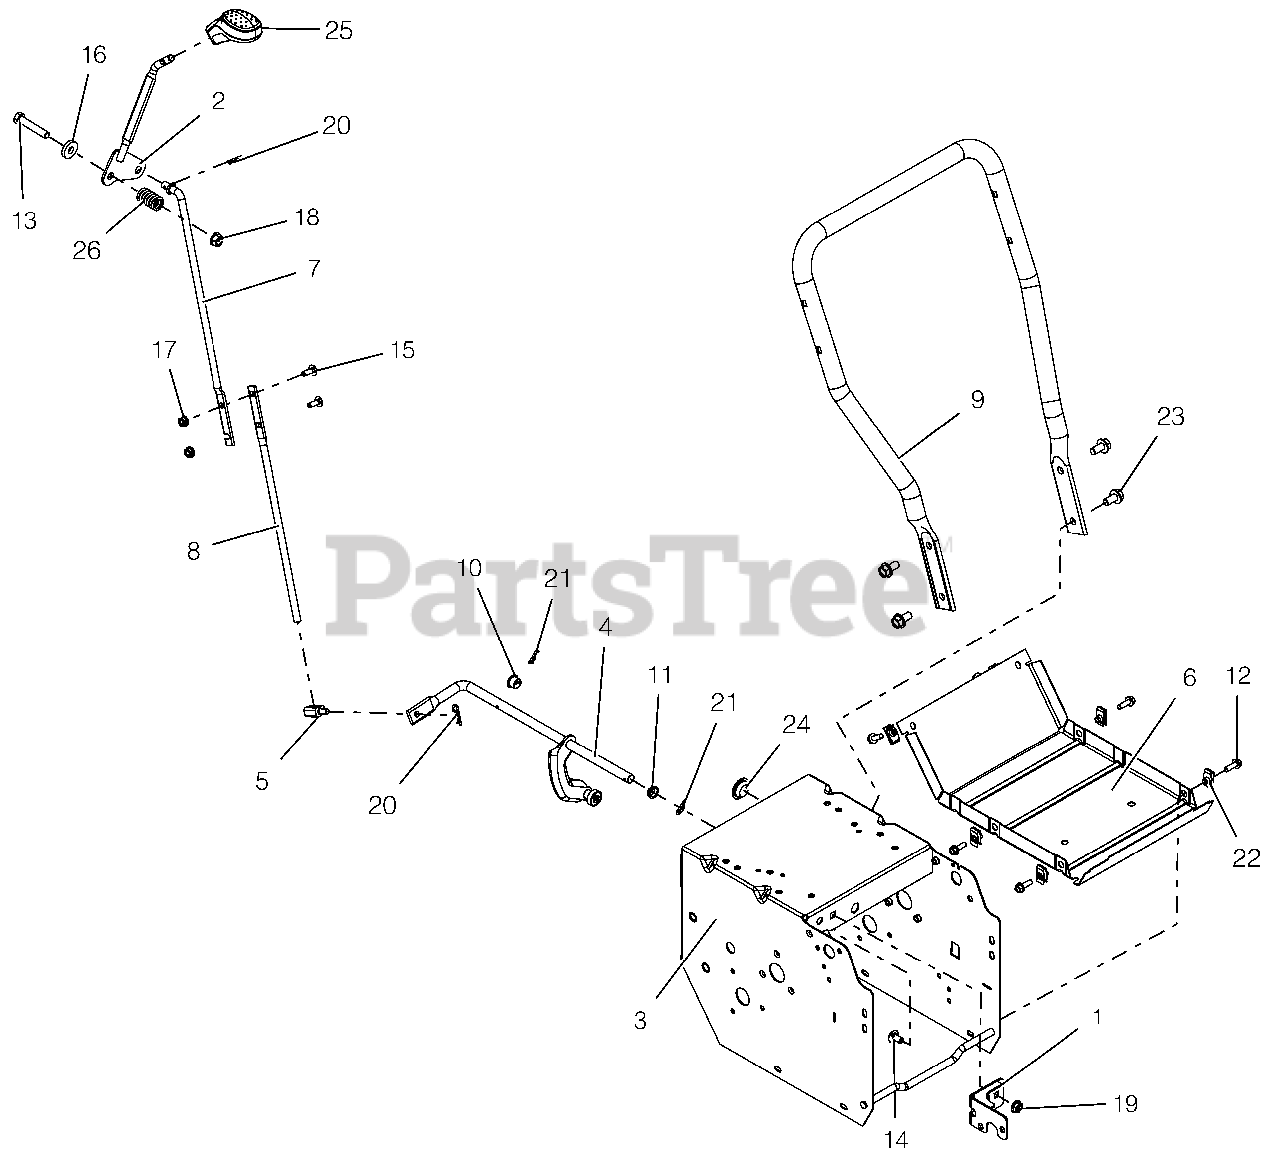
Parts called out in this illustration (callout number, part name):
1	WMT-FRAME BRACKET
2	LEVER, CONTROL-SHIFT(WELDMENT)
3	WELDMNET, FRAME-DELUXE 16"
4	ARM, SHIFT-SMALL DASH (ASSY)
5	PIVOT,SHIFT ROD .375-16(TRUNN)
6	COVER, BOTTOM
7	ROD, SHIFT - UPPER
8	ROD, SHIFT - LOWER(SMALL DASH)
9	HANDLEBAR, LOWER - SM DELUXE
10	BUSHING, POLYLINER-.50 SPLIT
11	BUSHING, POLYLINER-.50 SNAPIN
12	BLT-HEX .25-20X.75 HWH YZ GR5
13	@BLT-HEX .38-16X2.00 GR5 YWZC
14	@BLT-RHDSSQNK .31-18X.62 G5YZ
15	@BLT-RDHDSQNK .25-20X.75 G5YZ
16	WSHR-FL-STL .406X1.00X.188 YWZ
17	NUT-LK-CTR-FLG .25-20 YWZC
18	@NUT-LK-TOP-FLG .38-16 YWZC
19	@NUT-LK-TOP-FLG .31-18 YWZC
20	PIN-HAIR INT .08X.18X1.18 YWZC
21	CLIP, SPRING
22	NUT-RTNR .25-20X.56
23	BLT-SERHFWH .38-16X.75 YWZC
24	PLUG, HOLE - .875" NYLON
25	KNOB, CONTROL, DASH
26	SG-COMP .125X.781X1.250
